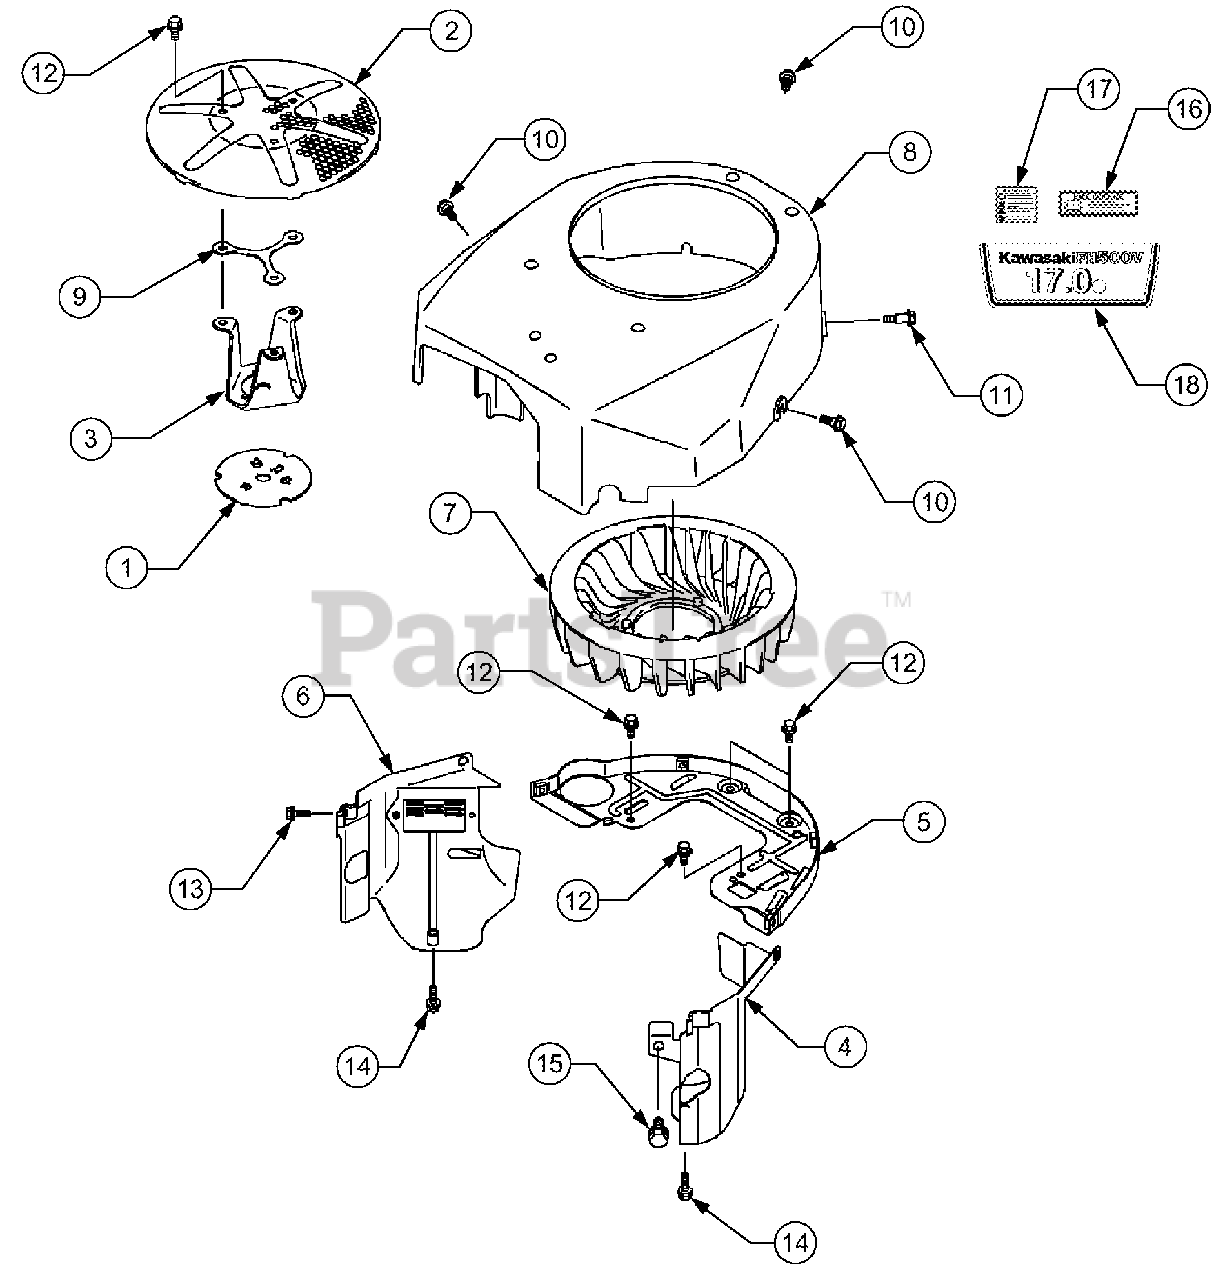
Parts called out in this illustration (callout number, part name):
2	Screen
3	Bracket, Comp
4	Shroud, Engine
5	Shroud, Engine
6	Shroud, Engine
7	Fan
11	Bolt
12	Bolt, Flanged
13	Bolt, Flanged
14	Bolt, Flanged
15	Bolt, Flanged
16	Label, Manual
17	Label, Warning
18	Label, Brand
